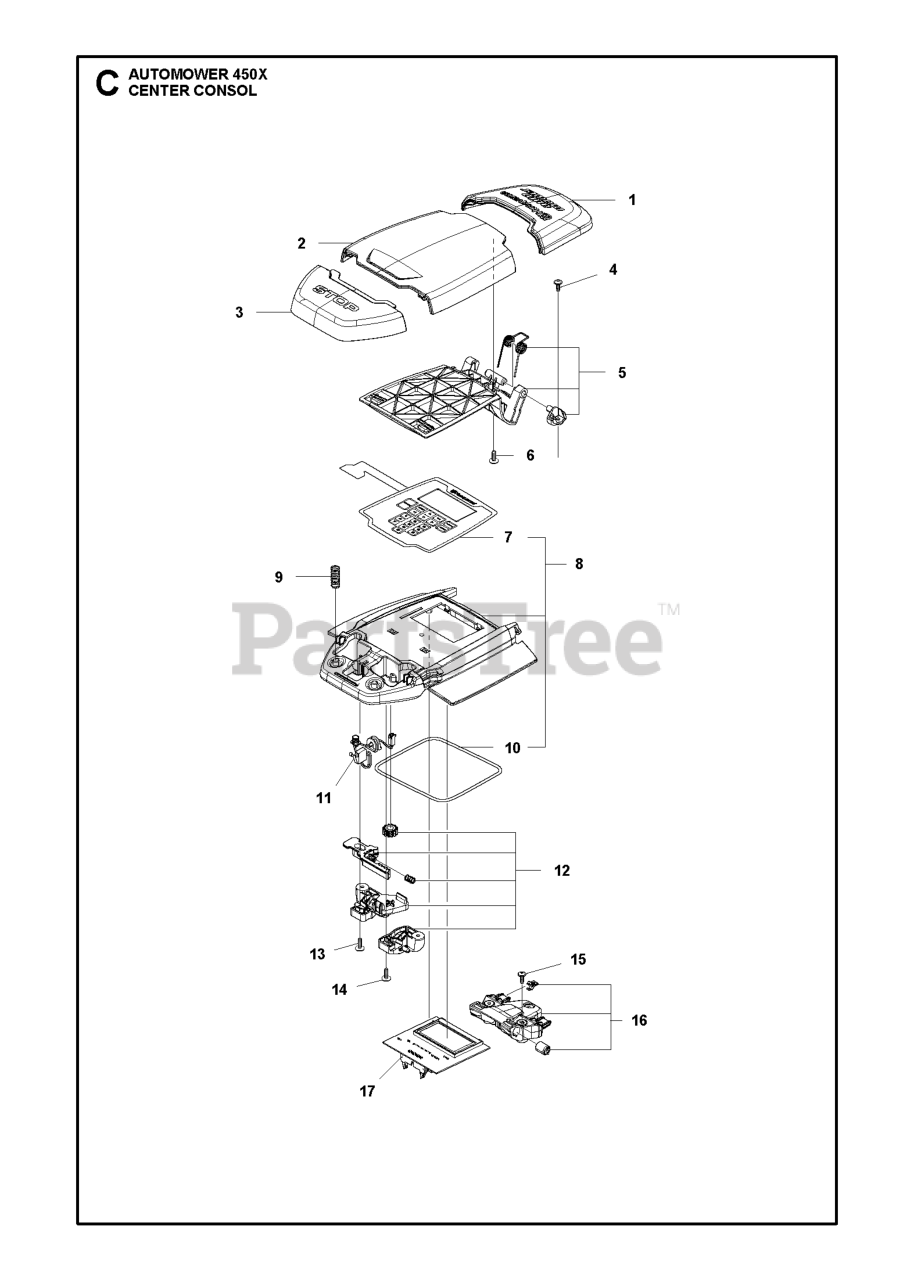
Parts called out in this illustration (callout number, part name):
1	COVER FRONT 450X BLACK
2	HATCH BLACK NCS S 9000-N
3	BUTTON STOP
4	SCREW 14MM
5	HINGE KIT KIT
6	SCREW 14MM
7	KEYBOARD 330X
8	COVER KIT DISPLAY ILLUMINATED
9	SPRING
10	SEALING STRIP
11	SWITCH STOP BUTTON NO ANCHOR
12	LOCK KIT
13	SCREW 14MM
14	SCREW 14MM
15	SCREW 14MM
16	SUPPORT KIT FRONT
17	PRINTED CIRCUIT ASSY PCBA MMI
